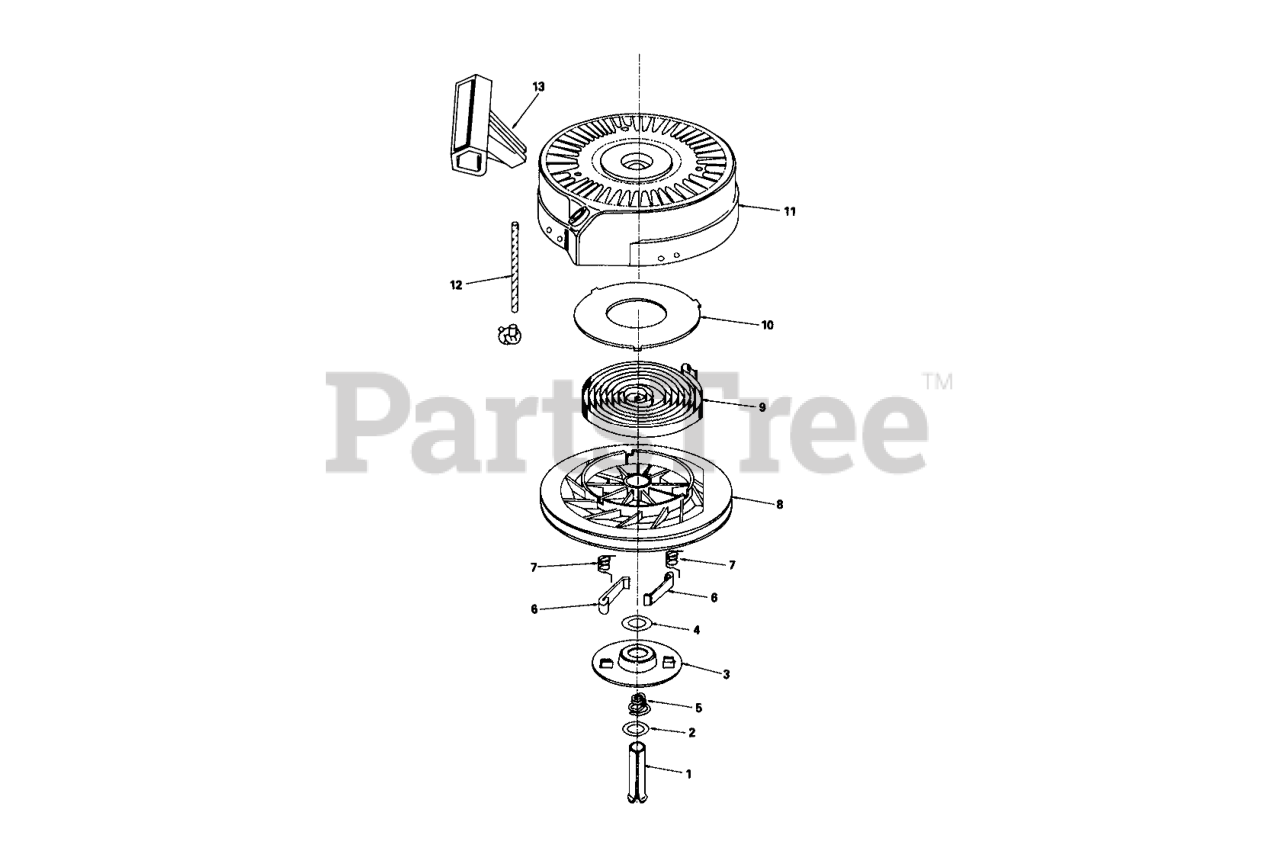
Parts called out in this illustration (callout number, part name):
1	Pin, Spring (Incl. Ref. #4)
3	Retainer
5	Brake Spring
6	Dog-Starter
7	Spring-Dog
8	Pulley
9	Rewind Spring
10	Cover-Spring
11	Housing-Starter
12	Rope-Starter (98 cut to length)
13	Handle-Starter
